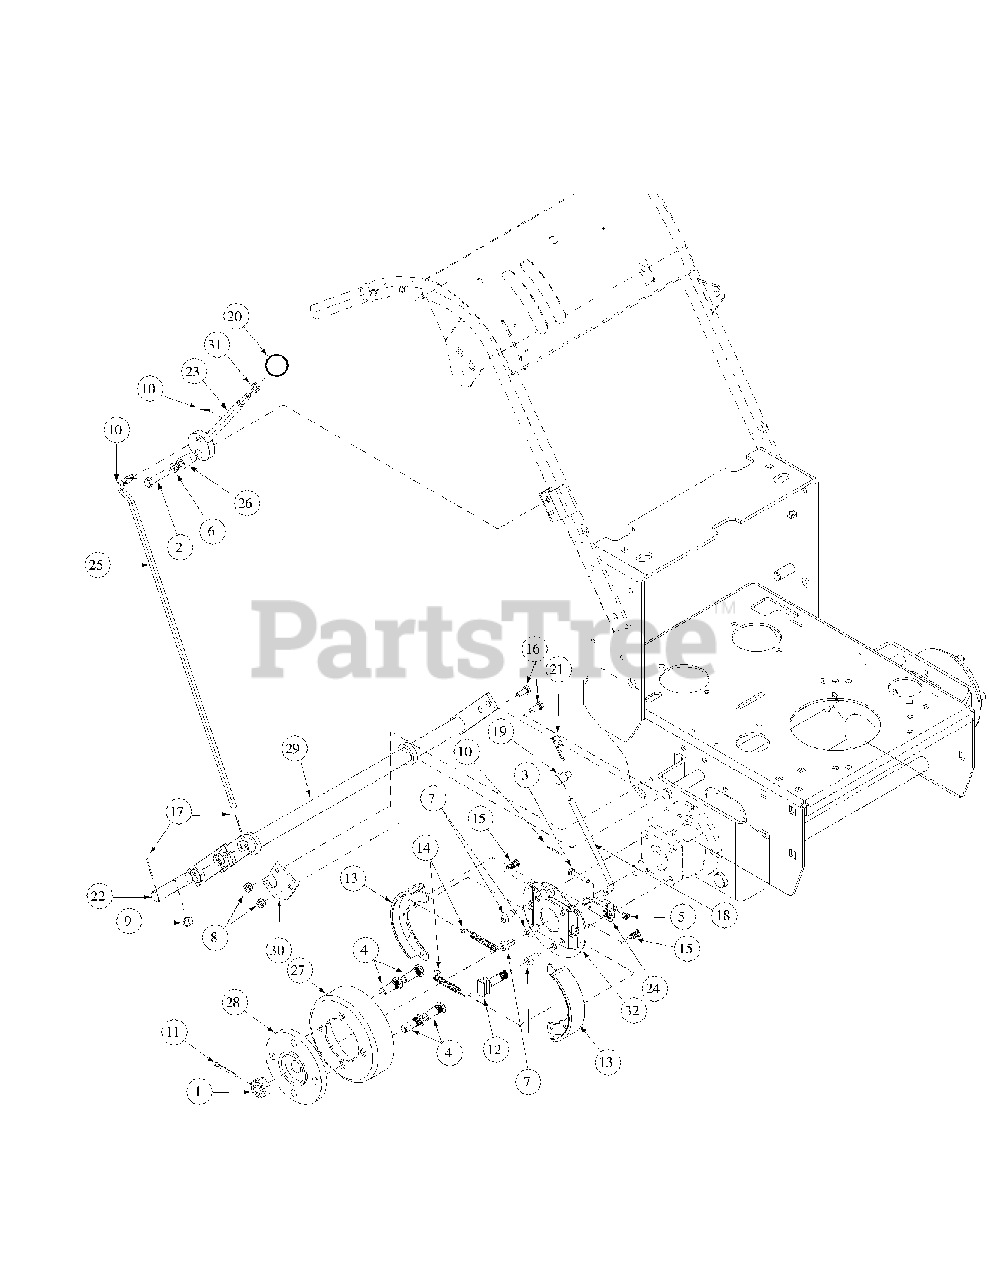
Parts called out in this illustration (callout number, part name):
1	Nut, Castle, 3/4-16
2	Capscrew, 3/8-16 x 1" Grade 5 Zinc
3	Cap Screw, 1/4-20 x 1.50, Grade 5
4	Bolt, Wheel, 1/2-20 x 1-3/8
5	Lock Nut, Nylon Insert, 1/4-20 Grade A
6	Lock Washer, 3/8 Zinc
7	Capscrew, Socket Button Hd., 3/8-16 x 3/4 Zinc
8	Nut, 5/16-18, Nylock
9	Nut, Nylon Insert, 3/8-16 Grade A
10	Cotter Pin, 3/32 x 3/4, Zinc
11	Cotter Pin, 5/32 x 1-1/2 Zinc
12	Brake Cam, Actuating
13	Brake Shoe w/Lining, 6 x 1-1/4
14	Brake Spring, Tension
15	Brake Spring, Anti-Vibration
16	Cap Screw, 5/16-18 x 3/4, Grade 5
17	Cotter Pin, 3/32 x 1, Zinc
18	Brake Rod
19	Swivel Joint
20	Knob, Red, Shift w/Insert
21	Hair Pin, 3/8"-1/2"
22	Joint, Brake Pull
23	Lever Assembly, Brake
24	Brake Clamp, Control Assembly, Hydro
25	Rod, Long Brake, Hydro WB
26	Pivot Spacer, Hydro WB
27	Brake Drum
28	Hub, Wheel Motor
29	Brake Shaft Assembly WT
30	Pivot Mount, Brake
31	Nut, 3/8-16, Jam, Grade 2
32	Brake Backing Plate
